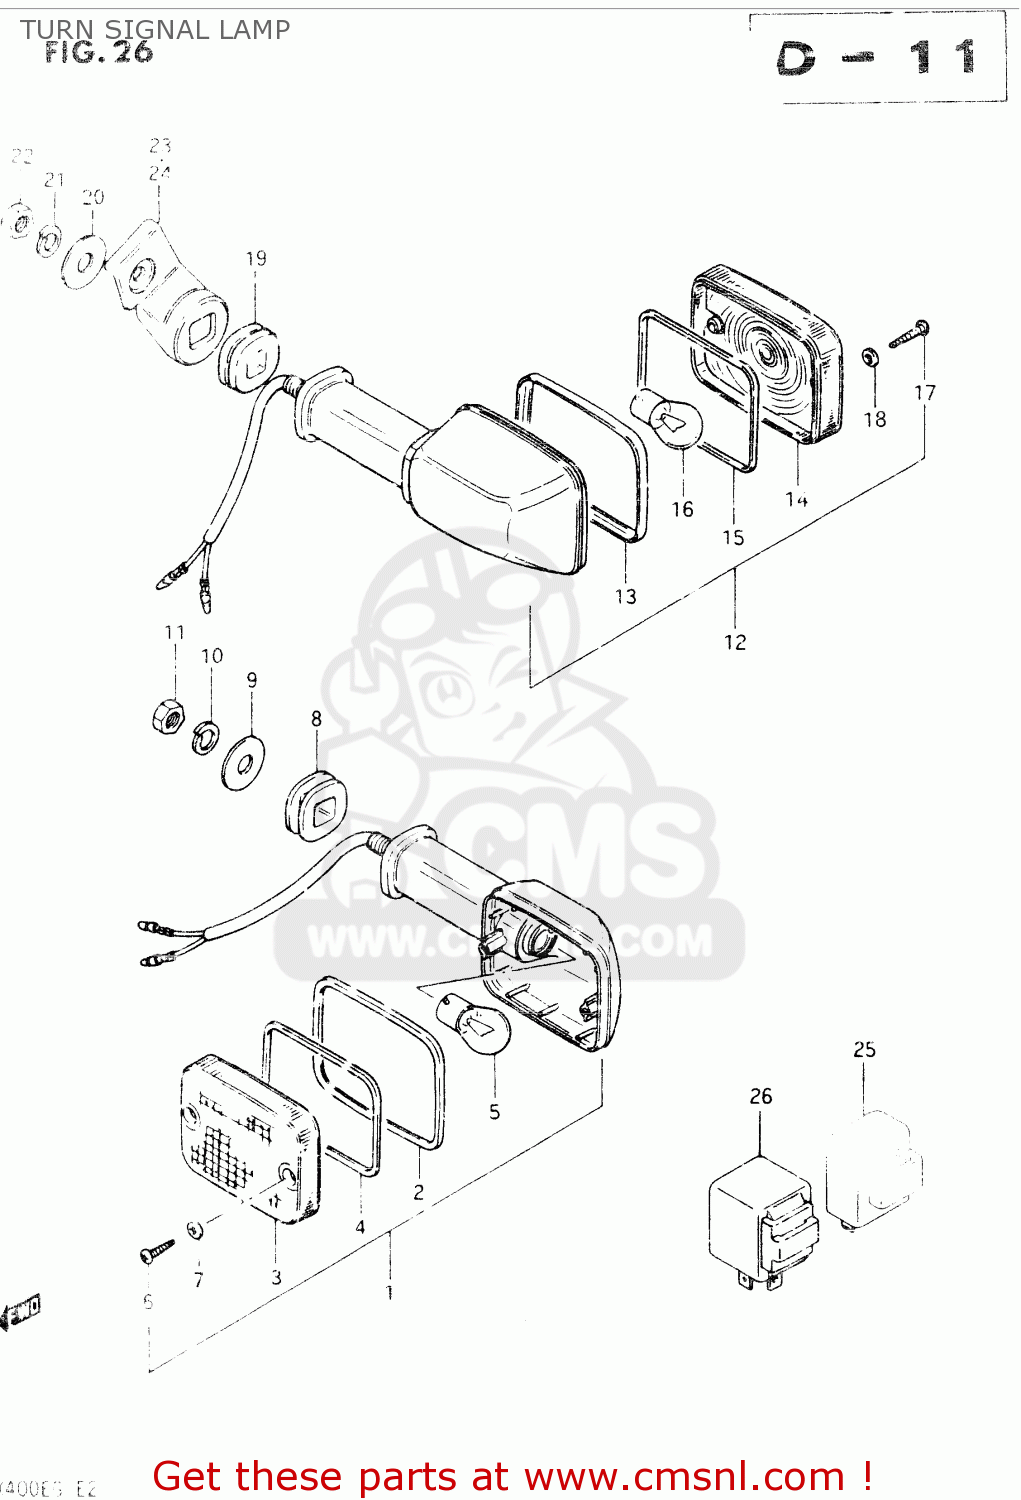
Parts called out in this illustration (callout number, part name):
1	LAMP ASSY,FR T
2	RIM
3	LENS
4	GASKET (NAS)
5	BULB(12V21W)
6	SCREW
7	GASKET (NAS)
8	CUSHION
9	WASHER (10.5X30X2.3)
10	LOCK WASHER
11	NUT
12	LAMP, REAR TURN SIGNAL
13	RIM
14	LENS
15	GASKET (NAS)
16	BULB(12V21W)
17	SCREW
18	GASKET (NAS)
19	CUSHION
20	WASHER (10.5X30X2.3)
21	LOCK WASHER
22	NUT
23	BRACKET,REAR TURN SIGNAL
24	BRACKET,REAR TURN SIGNAL
25	RELAY ASSEMBLY,TURN SIGNAL
26	RELAY ASSY,TUR
